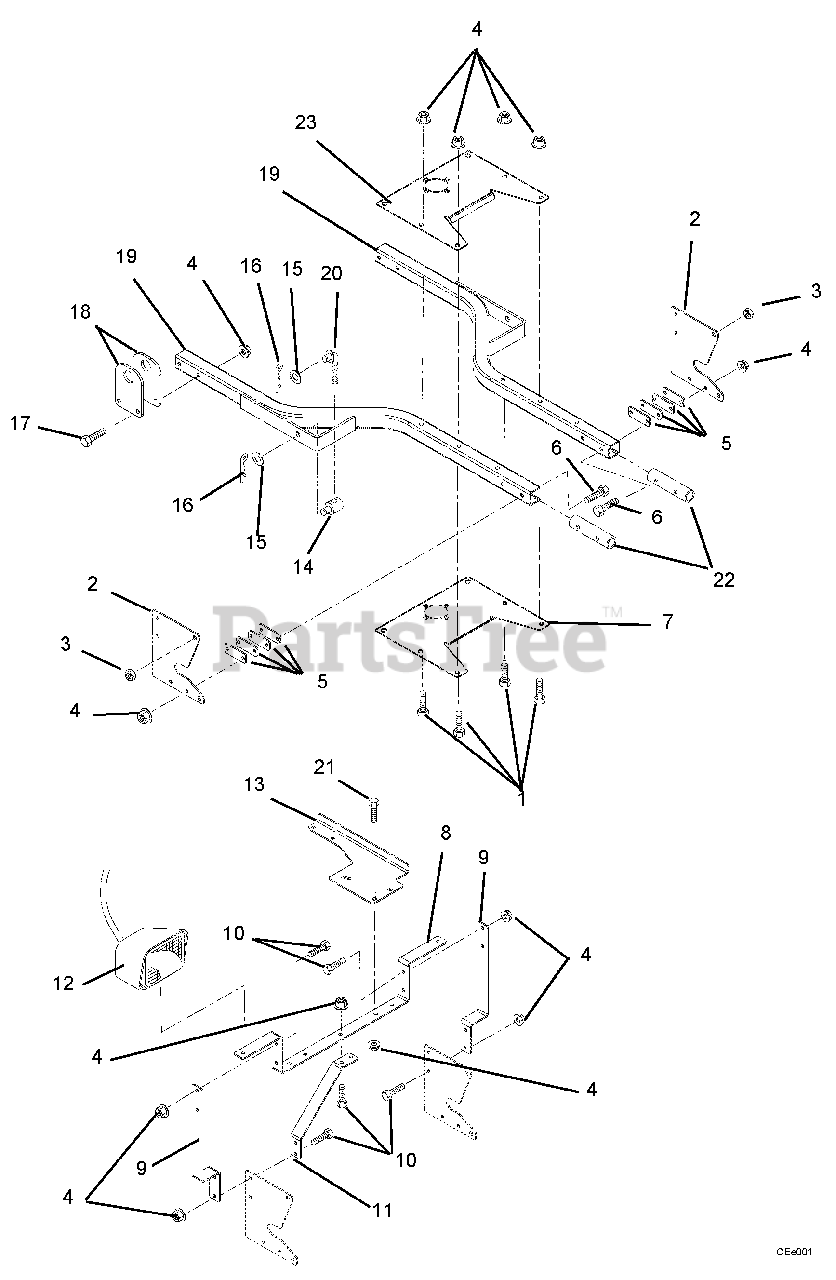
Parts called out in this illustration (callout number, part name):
1	@BLT-HEX .38-16X2.50 GR5 YWZC
2	PLATE,SNO-THRO MOUNT
3	@NUT-LK-CTR .50-13 YWZC
4	@NUT-LK-TOP-FLG .38-16 YWZC
5	PLATE,SHIM
6	@BLT-HEX .38-16X3.00 GR5 YWZC
7	PLATE,SUB-FRAME
8	LIGHT-BAR,SNO-THRO
9	SUPPORT,LIGHT BAR
10	@BLT-HEX .38-16X1.00 GR5 YWZC
11	GUSSET,LIGHT BAR
12	HEADLIGHT
13	BKT,DEFLECTOR CNTRL
14	TRUNNION-.50
15	WSHR-FL-STL .531X1.250X.10 YWZ
15	@WSHR-FL-STL.50X1.25X.083 YWZC
16	PIN, HAIR, EXT - #16 YWZC
17	@BLT-HEX .38-16X2.50 GR5 YWZC
18	BRKT,PIVOT
19	WMT,SUB-FRAME TUBE
20	LINK, LIFT
21	@BLT-RDHDSQNK .38-16X1.00 G5YZ
22	TUBE, ANTI-CRUSH
23	PLATE, SUBFRAME - TOP
